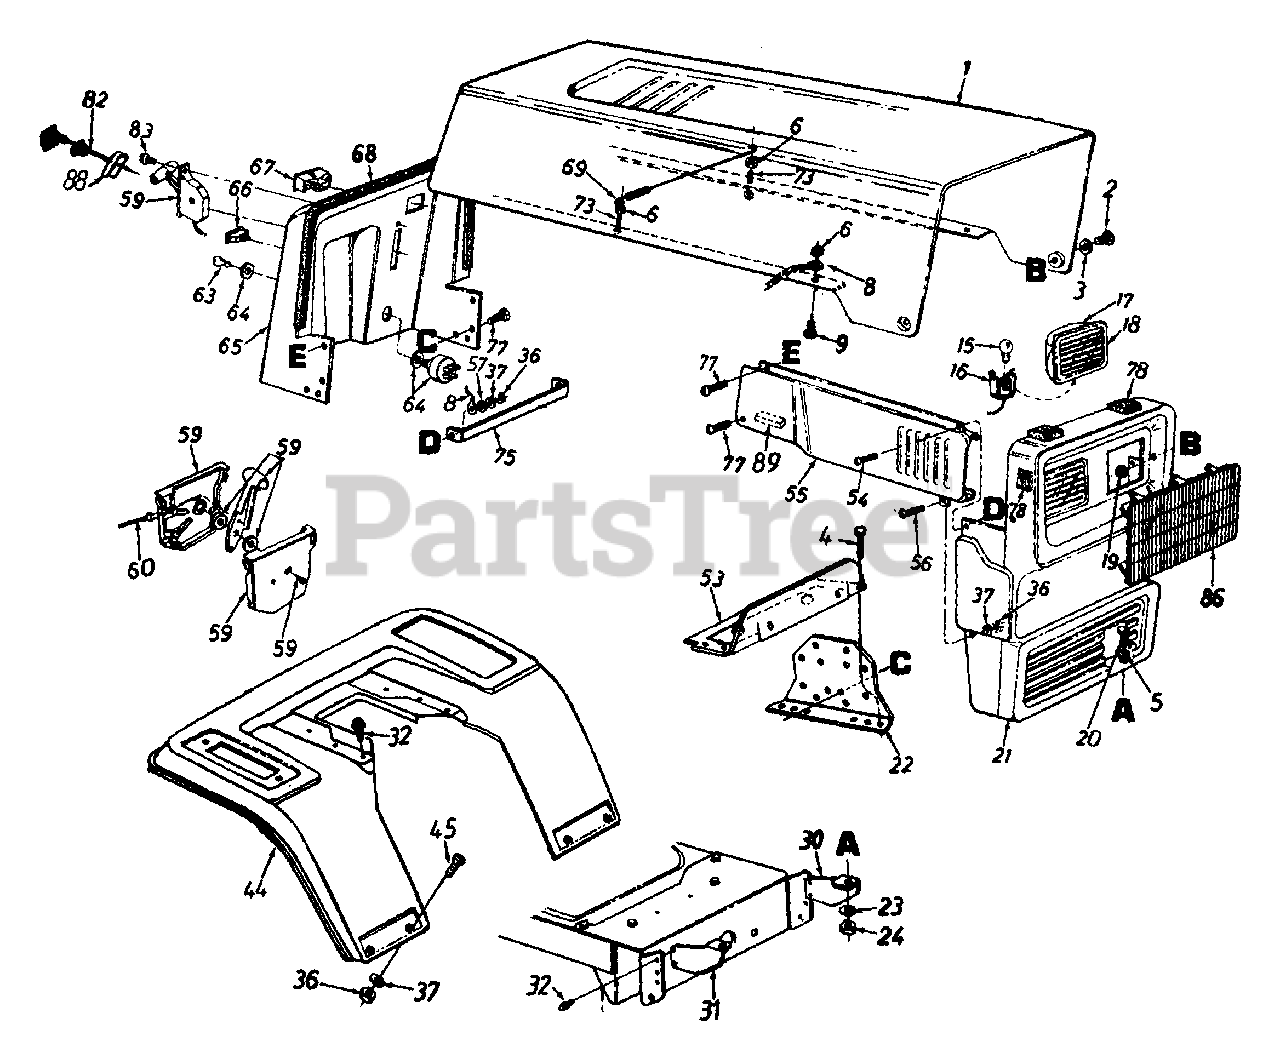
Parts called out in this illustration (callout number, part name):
3	Washer .39" I.D. x .62"
4	Hex Wash. Hd. B-Tap Scr. 5/16-18 x .5" Lg.
5	Fl-Wash. .344" I.D. x 1" O.D.
6	Hex Sems Nut #10-24 Thd.
8	Hood Stop
9	Truss Hd. Scr. #10-24 x 1/2"
15	Lamp
16	Twist Lock - Lamp Socket
17	Headlight Housing
18	Lens
19	L-Nut 1/4-28 Thd.
20	Hex Bolt 5/16-18 x .75" Lg.
24	Hex Nut 5/16-18 Thd.
30	Grille Mount Brk't.- L.H.
36	Hex Nut 1/4-20 Thd.
37	L-Wash. 1/4" I.D.
55	Side Cover - R.H.
57	Fl-Wash. .281" I.D. x .73" O.D.
59	Throttle Control Box Ass'y.
60	Throttle Control Wire (B&S)
63	Ignition Key
64	Ignition Switch
67	Ammeter
68	Trim Strip - 31"
69	Hood Spring
73	Hex Scr. #10-24 x 1.0" Lg.
75	Tie Strap - Grille/Side Panel
77	Hex Wash. Hd. Tap Scr. 1/4 x .75" Lg.
78	Foam Strip 3/8 x 1-1/8" x 1-1/2" Lg.
82	Choke Control
83	Truss Mach. AB-Tap Scr. #10 x .5" Lg.
86	Headlight Bezel
88	Choke Retainer
89	Rubber Strip
